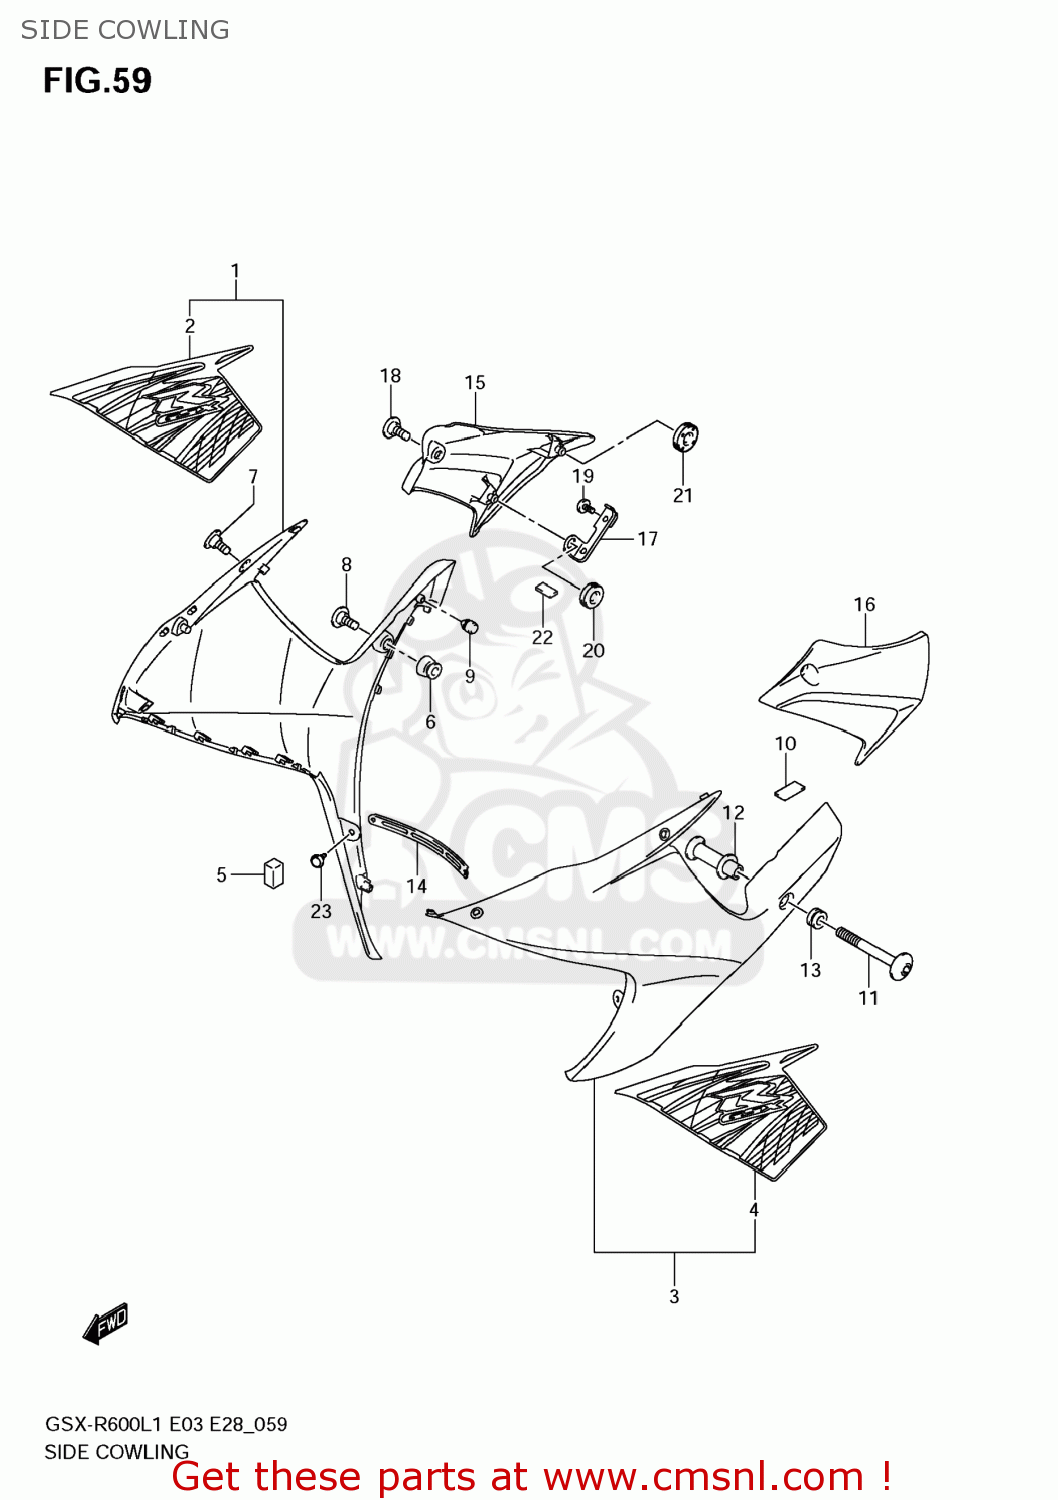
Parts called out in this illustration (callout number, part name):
1	COWLING,SIDE,R(BLACK)
2	TAPE,SIDE COWLING,R
3	COWLING,SIDE,L(BLACK)
4	TAPE,SIDE COWLING,L
5	CUSHION,SIDE C
6	CUSHION,UNDER COWLING,L
7	SCREW(5X13)
8	BOLT(6X20)
9	CUSHION
10	CUSHION,FUEL TANK NO.2
11	SCREW,SIDE COWL,L
12	SPACER,SIDE COWL,L
13	CUSHION
14	PLATE,UNDER COWL CTR
15	COVER,SIDE COWLING,R
16	COVER,SIDE COWLING,L
17	BRACKET,COVER SIDE,R
18	SCREW(5X13)
19	SCREW(6X12)
20	CUSHION
21	CUSHION
22	CUSHION
23	CLIP
